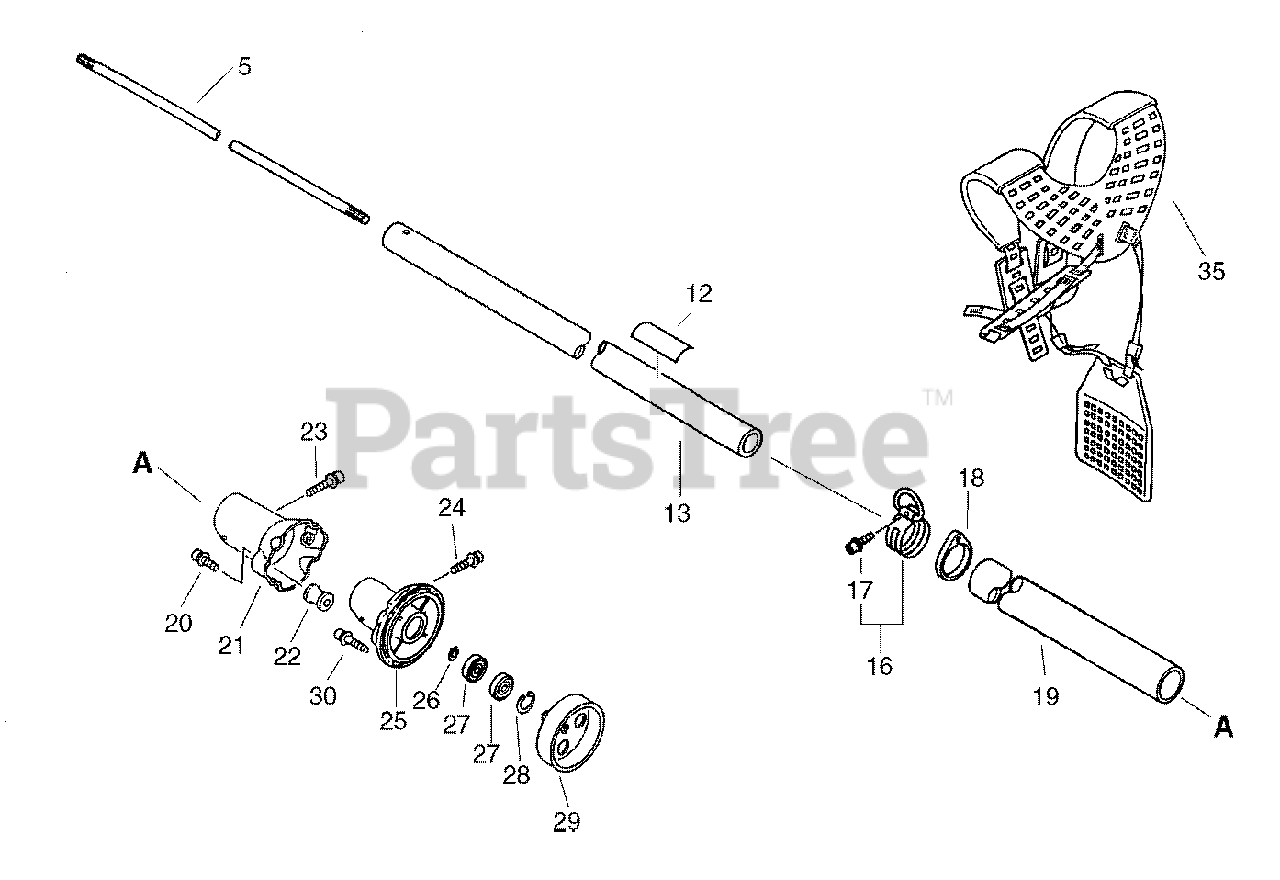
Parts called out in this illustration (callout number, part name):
5	DRIVESHAFT
12	LABEL - CAUTION
13	PIPE, MAIN
16	HANGER KIT
17	SCREW - 5X20
18	CLIP
19	SWIVEL, D.S.HOUS
19	PIPE, MAIN
20	SCREW - 5X14
21	CASE, CLUTCH
23	SCREW - 5X35
24	SCREW - 5X30
25	CASE, FAN
26	RING, RETAINING - 15
27	BEARING, BALL - 6202
28	RING, RETAINING - 35
29	DRUM, CLUTCH
30	SCREW - 5X20
35	HARNESS, SHOULDER
